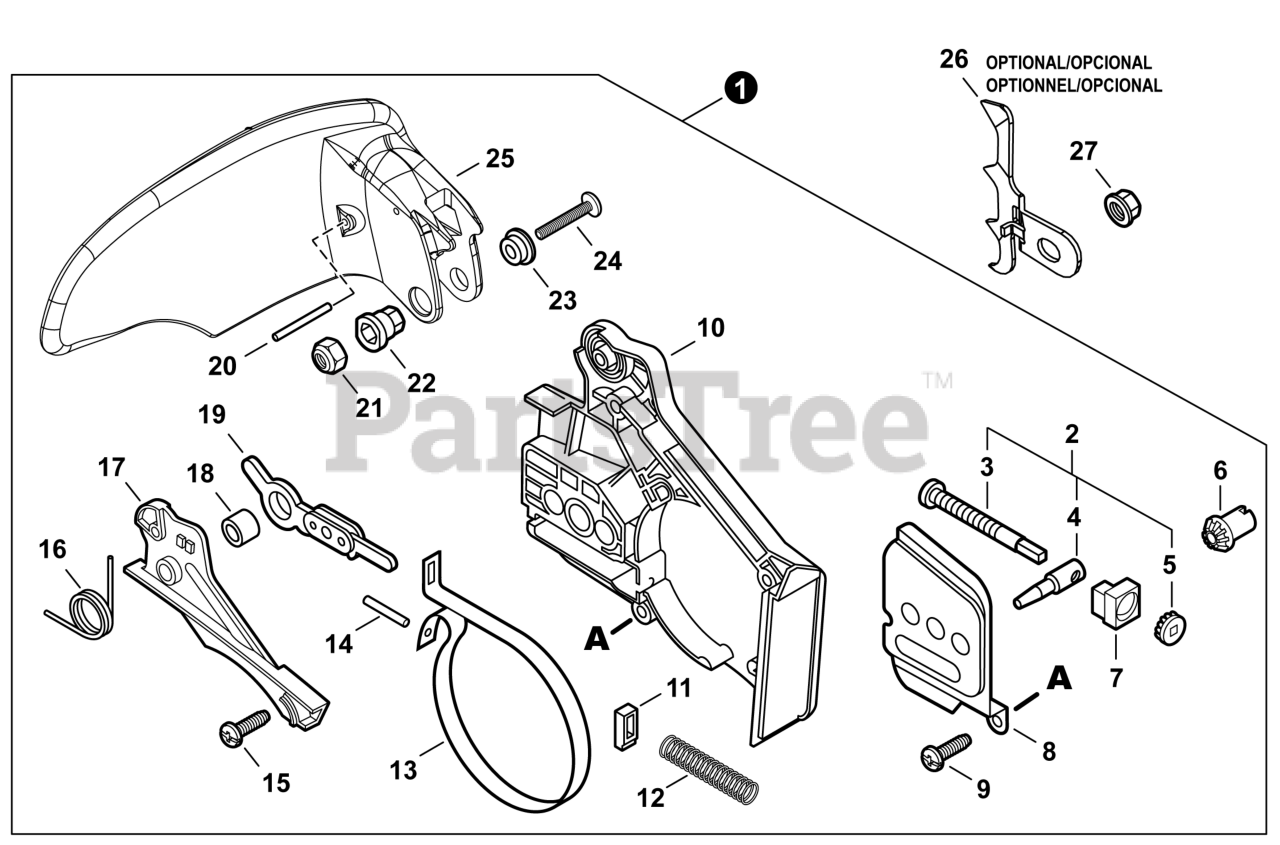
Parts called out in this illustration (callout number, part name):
1	BRAKE ASSY, CHAIN
2	TENSIONER KIT, CHAIN
3	SCREW, CHAIN TENSION
4	TENSIONER, CHAIN
5	GEAR, BEVEL
6	GEAR, BEVEL
7	COLLAR 8
8	PLATE, GUIDE - OUTER
9	SCREW 4x12
10	GUARD, SPROCKET
11	GUIDE
12	SPRING, COMPRESSION
13	BAND, BRAKE
14	PIN, SPRING 3x9.8
15	SCREW 4x12
16	SPRING, TORSION
17	COVER, BRAKE
18	SPACER 8x12x9
19	CONNECTOR, BRAKE
20	PIN 3x26
21	NUT, LOCK M5
22	COLLAR 5
23	COLLAR 5.3x10x13xL5
24	SCREW 5x32
25	BRAKE, CHAIN
26	SPIKE, BUMPER
27	NUT, FLANGE M8x1.25
